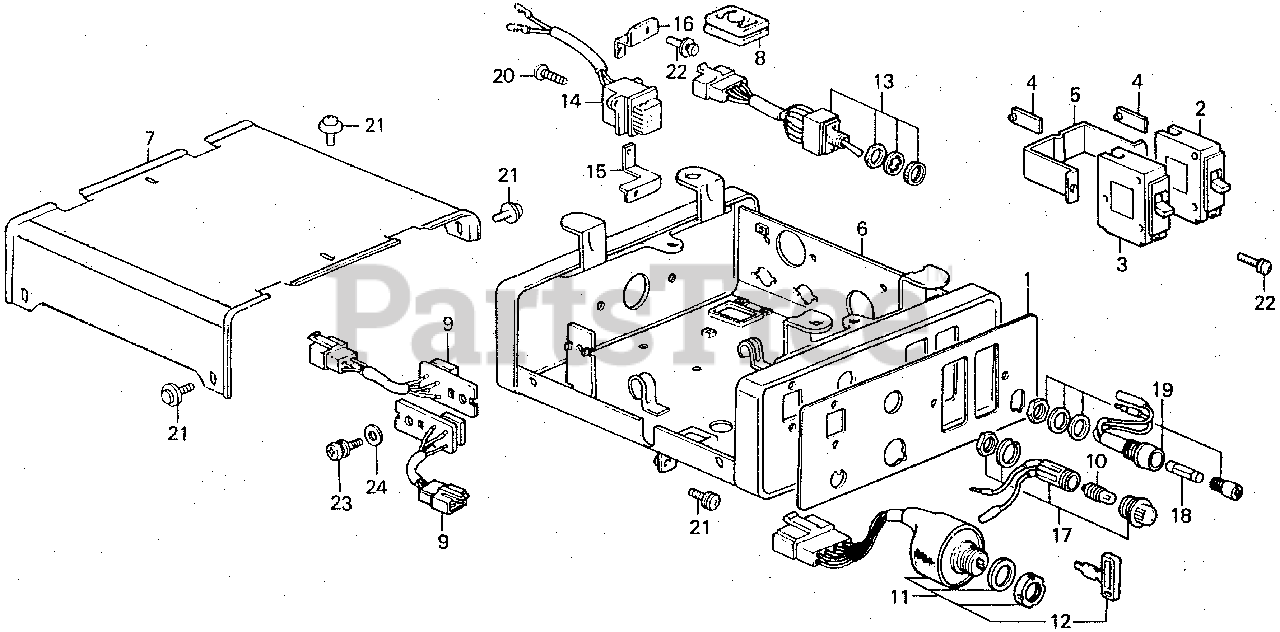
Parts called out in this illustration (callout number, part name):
1	PANEL, BOX
2	BREAKER, CIRCUIT (33A) (NOT AVAILABLE)
3	BREAKER, CIRCUIT (16.5A) (NOT AVAILABLE)
4	TERMINAL, BREAKER
5	SUPPORT, BREAKER (NOT AVAILABLE)
6	BOX, CONTROL *R8* (BRIGHT RED)
7	COVER, BOX (UPPER) *R8* (BRIGHT RED)
8	GROMMET, REMOTE CONTROL
9	STACK ASSY., DIODE
10	BULB (24V2W)
11	SWITCH ASSY., COMBINATION
12	KEY
13	SWITCH ASSY., CONTROL
14	METER, FREQUENCY
15	HOLDER A, FREQUENCY METER
16	HOLDER B, FREQUENCY METER
17	SOCKET ASSY., PILOT LAMP
18	FUSE (15A)
19	HOLDER, FUSE (NOT AVAILABLE)
20	SCREW, PAN (3X8)
21	SCREW-WASHER (5X12)
22	SCREW-WASHER (4X12)
23	SCREW-WASHER (6X12)
24	WASHER, PLAIN (6MM)
